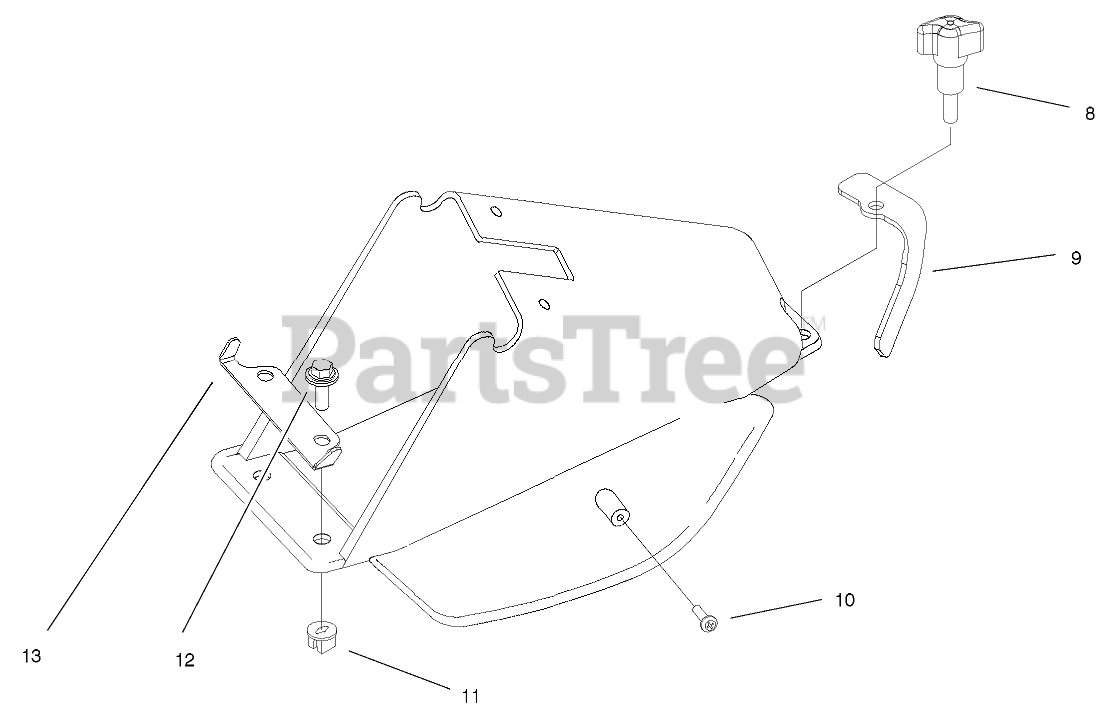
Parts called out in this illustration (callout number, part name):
8	Knob (only on: 20021)
9	Clamp-Door (only on: 20021)
10	Screw-PPH (only on: 20021)
11	Grommet (only on: 20021)
12	Screw-HWH (only on: 20021)
13	Bracket-Mount,Chute (only on: 20021)
